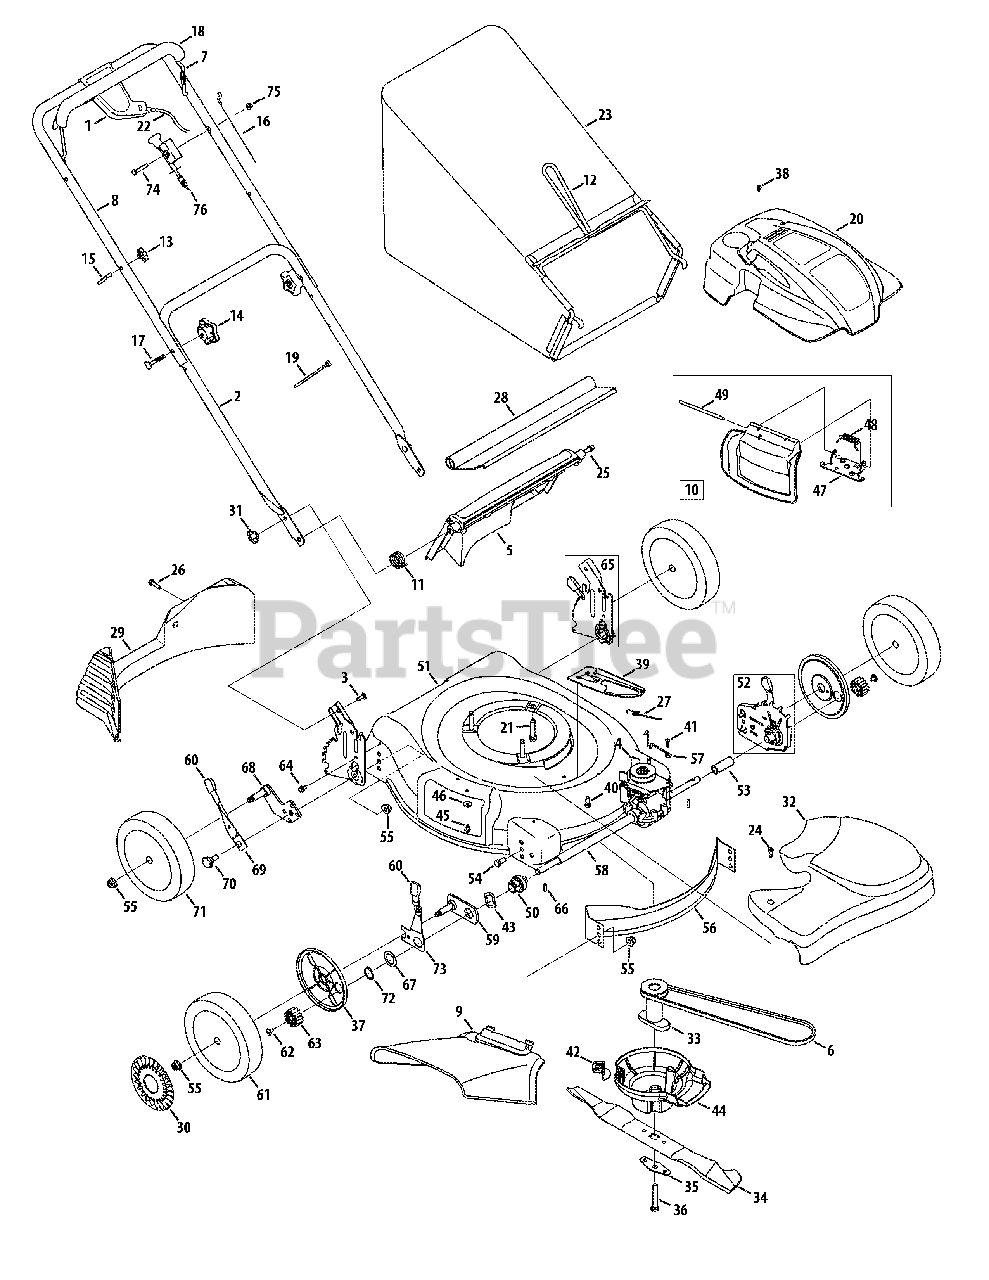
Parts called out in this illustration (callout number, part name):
1	Drive Control Assembly
3	Carriage Bolt 1/4-20
4	Transmission Assembly
5	Rear Discharge Door
7	Blade Control
8	Upper Handle
9	Chute Deflector
10	Mulch Plug Complete
11	Torsion Spring - RH
12	Grass Bag Frame
13	Handle Knob
14	Handle Knob
16	Control Cable
17	Carriage Bolt 5/16-18 x 2.0
18	Bail Cover
19	Cable Tie
20	Engine Shroud
21	Self-Tapping Sems Screw
22	Drive Cable
23	Grassbag
24	Shoulder Screw # 12 -24
26	Screw, 1/4-15 x 1.00
27	Extension Spring
28	Rear Trailing Shield
29	Rear Baffle
30	Hub Cap
31	Wing Nut
32	Transmission Cover
33	One Piece Blade Adapter
34	21" Mulching Blade
35	Blade Bell Support
36	Hex Screw 3/8-24 x 2.50
37	Wheel Dust Cap
38	Scr., #12-16 x 1.00
39	Cable Mount Bracket
40	Screw, 1/4-14 x .625
41	Screw, .159 OD x .610
42	Engine Baffle Bracket
43	Washer, Wave, 1.5 x 1.0 x .029
44	Engine Baffle
45	TT Screw 1/4-20 x 0.5
46	Bell Washer.265 x 0.75
47	Deflector Chute Adapter
48	Torsion Spring
49	Hinge Pin
50	Bearing Assembly
52	Height Adjustment Ass’y - RH
52	Height Adjustment Ass’y - LH
53	Sleeve Spacer, 1.8" Lg.
54	Hex Screw, 3/8-16 x.75
55	Flange Lock Nut, 3/8-16
56	Front Baffle
57	Belt Keeper Wire
58	Sleeve Spacer, 9.10" Lg.
59	Pivot Plate Assembly
60	Adjustment Knob
61	Front Wheel, 8 x 2.125
62	Screw, 1/4-20 x .390
63	Gear 14T RH FWD
63	Gear 14T LH FWD
64	TT Scr. w/Washer 1/4-20 x.625
65	Handle Bracket Assembly - RH
65	Handle Bracket Assembly - LH
66	Dowel Pin
68	Pivot Arm Assembly - RH
68	Pivot Arm Assembly - LH
69	Rear Spring Lever
70	Shoulder Scr., 500 Dia. x. 385
71	Rear Wheel, 8 x 2.125
72	Snap Ring
73	Front Lever - RH
73	Front Lever - LH
74	Hhcs, 1/4-20 x 1.50
75	Nut, Flglk, 1/4-20
76	Choke Cable
